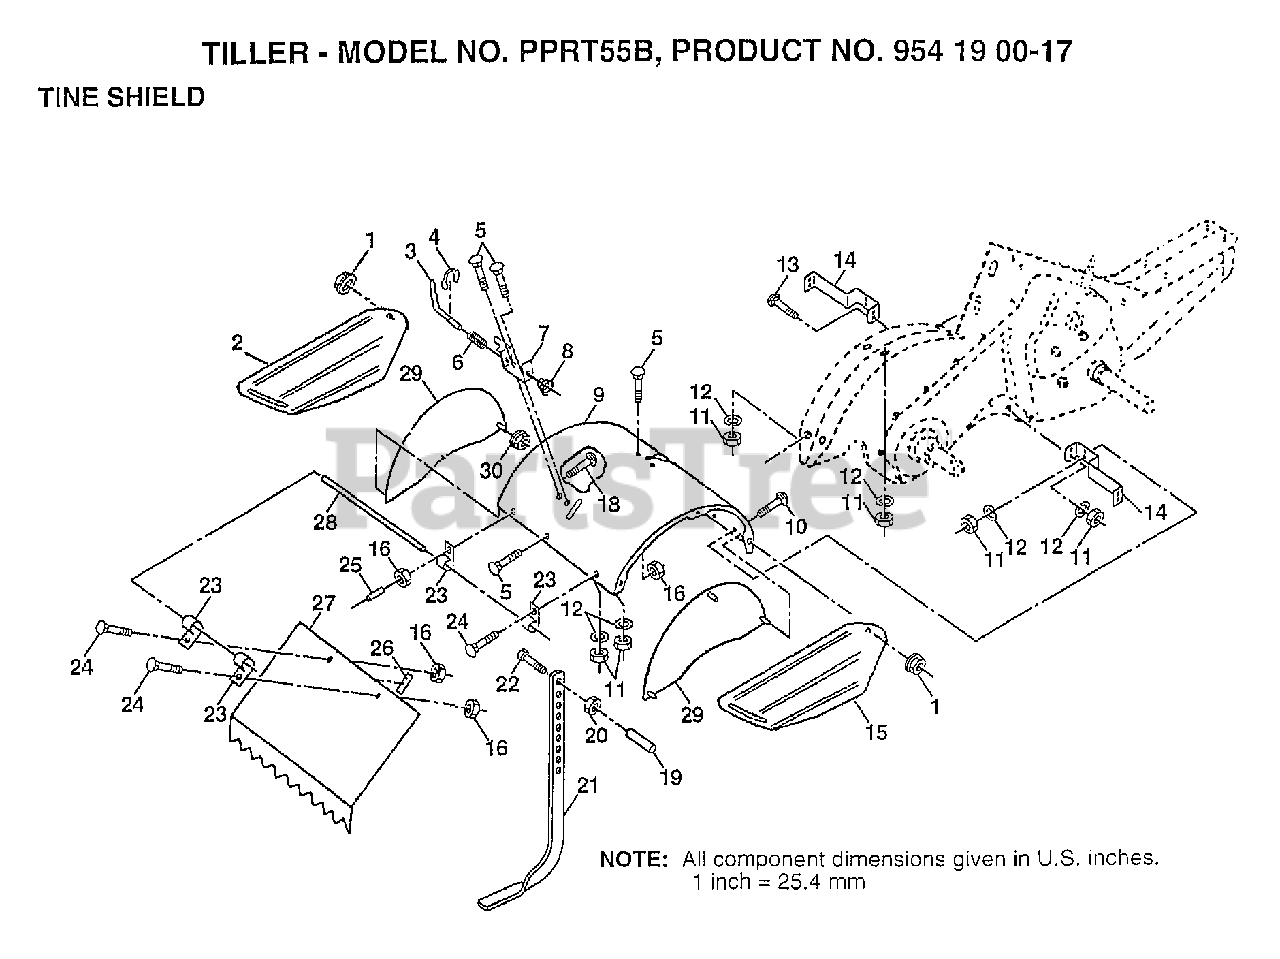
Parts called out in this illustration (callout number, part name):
1	NUT
2	"SHIELD,SIDE,O.LH"
3	STAKE PIN TI
4	KLIP RING TI
5	BOLT
6	SPRING TI
7	LATCH BRACKET TI
8	SPRING CRT
9	TINE SHIELD
10	BOLT
11	NUT.HEX.5/16-18
12	LOCKWASHER
13	BOLT
14	"BRACKET,SHIELD"
15	SHIELD SIDE O.RH
16	NUT
18	BOLT
19	GRIP CRT
20	NUT.HEX.3/8-16UNC
22	BOLT
23	HINGE CRT
24	BOLT
25	VINYL CAP TI
26	PAD IDLER TI
27	LEVELING SHIELD
28	PIN HINGE
29	SIDE SHIELD
30	LOCKNUT TI
